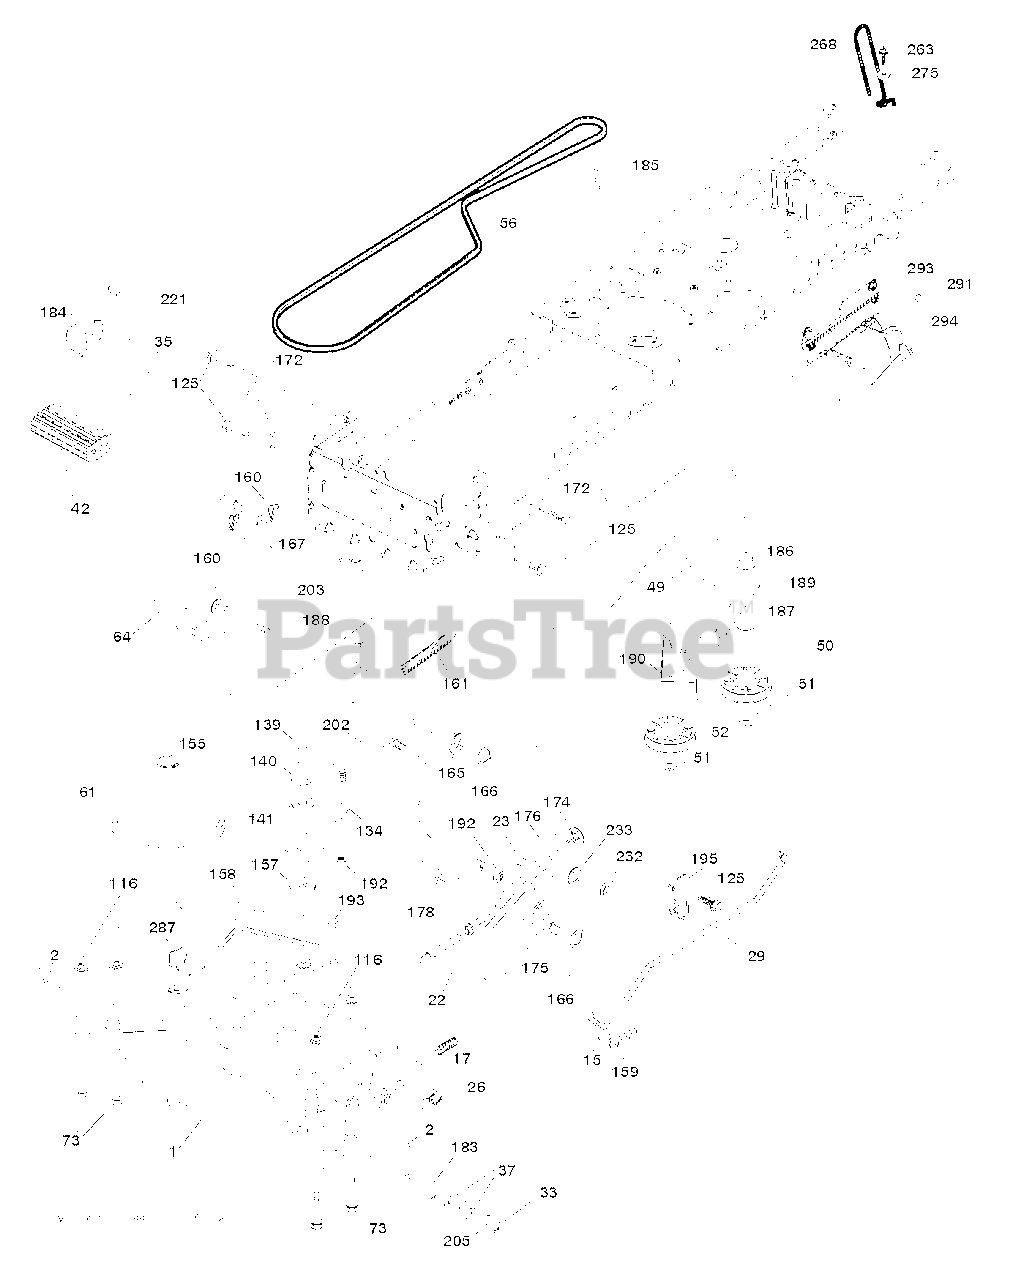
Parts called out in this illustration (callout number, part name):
2	SQUARE KEY
15	WASHER
17	SPRING.BRAKE.PEERLESS.TEX
23	KNOB.DUCKHEAD.1/2
26	SPRING.BRAKE.RTN.GR.DR
29	ROD.BRAKE.PEERLESS
35	ROD.CNTRL.PARK.PREDATOR.LT.TEX
42	PEDAL COVER T
50	IDLER.FLAT.910.OFFSET
51	NUT LOCK FLG 3/8-16 UNC
52	IDLER.V-GROOVE.910.OFFSET
56	BELT, V GROUND DRIVE 95 25
61	PULLEY
64	SHAFT.ASM.PEDAL.BRAKE.
116	NUT LOCK HEX FLANGE 5/16-18
125	SCREW
139	BOLT 1/4-28X3/4
140	LOCKWASHER
155	RETAINING RING LT
157	WASH-SHFT PLT LT
158	KEEPER.PMS.18/20.D4365
159	COTTER PIN
160	RETAINER CLIP
161	SPRING, RETURN LT
165	BUSHING.SHAFT.BRAKE.HAND
166	NUT.PUSH.625
167	LATCH.BRAKE.SPRING
172	STRAP.TRQ.LH.GEAR.DRIV
174	NUT.PUSH.500.2006
175	SHAFT ASM SHIFT
176	ARM.CLEVIS.ROD.SHIFT
178	SPRING.SHIFT.GT2006
183	SPACER AXLE
184	HANDLE.PARKING.BRK.PRED.LT.RED
186	SPACER.RETAINER
187	WASHER 12/32X2X10GA
188	RP LINK.CLUTCH.GROUND.DRIVE
189	BELLCRANK.GROUND.DRIVE.TEX.
190	KEEPER.BELLCRANK.DRIVE
192	NUT LOCK CENTER 1/4 -28 FNTHD
193	SCREW 5/16"
195	BRKT.ROD.BRAKE.PEERLES
202	LINK.SHIFT.PMST.18" (SPG1286)
203	WASHER
221	RETAINER.SPRING.CLIP.H
232	BOLT FIN HEX 7/16-14 X 1
233	WASHER SERRATED
263	SCREW, 3/8-16X3/4
268	GUARD MUFFLER
275	WASHER
287	KEEPER.PULLEY.T/A.7.04
291	SHOULDER BOLT 5/16-18TT
293	HINGE RIGHT
294	GUARD RIGHT
